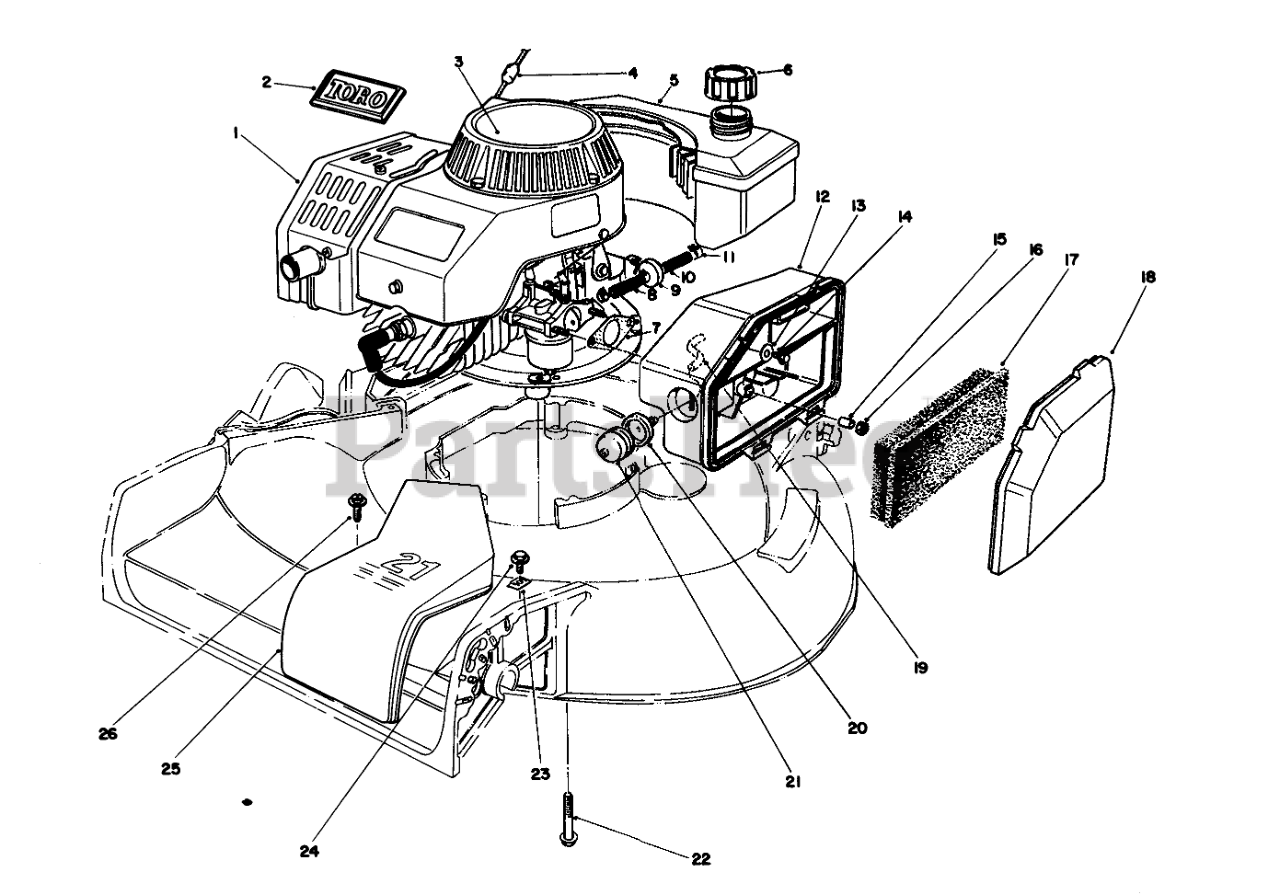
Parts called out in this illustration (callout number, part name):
1	Engine
2	TORO LOGO PLT
3	DECAL
5	FUEL TANK ASM
6	GAS CAP ASM
7	GASKET-AIR CLEANER
8	HOSE-FUEL
9	FILTER-FUEL
10	HOSE-FUEL
11	CLAMP-FUEL LINE
12	BODY-AIR CLEANER
13	WASHER-FLAT
14	SCREW-HH
15	SPACER
17	ELEMENT-AIR CLEANER
18	COVER-AIR CLEANER
19	HOSE-PRIMER
20	BODY-PRIMER
21	Bulb Primer
22	SCREW-HHF, WHIZ
23	CLAMP-CABLE
24	SCREW-HWHTF
25	BELT COVER 21" S D
26	SCREW
